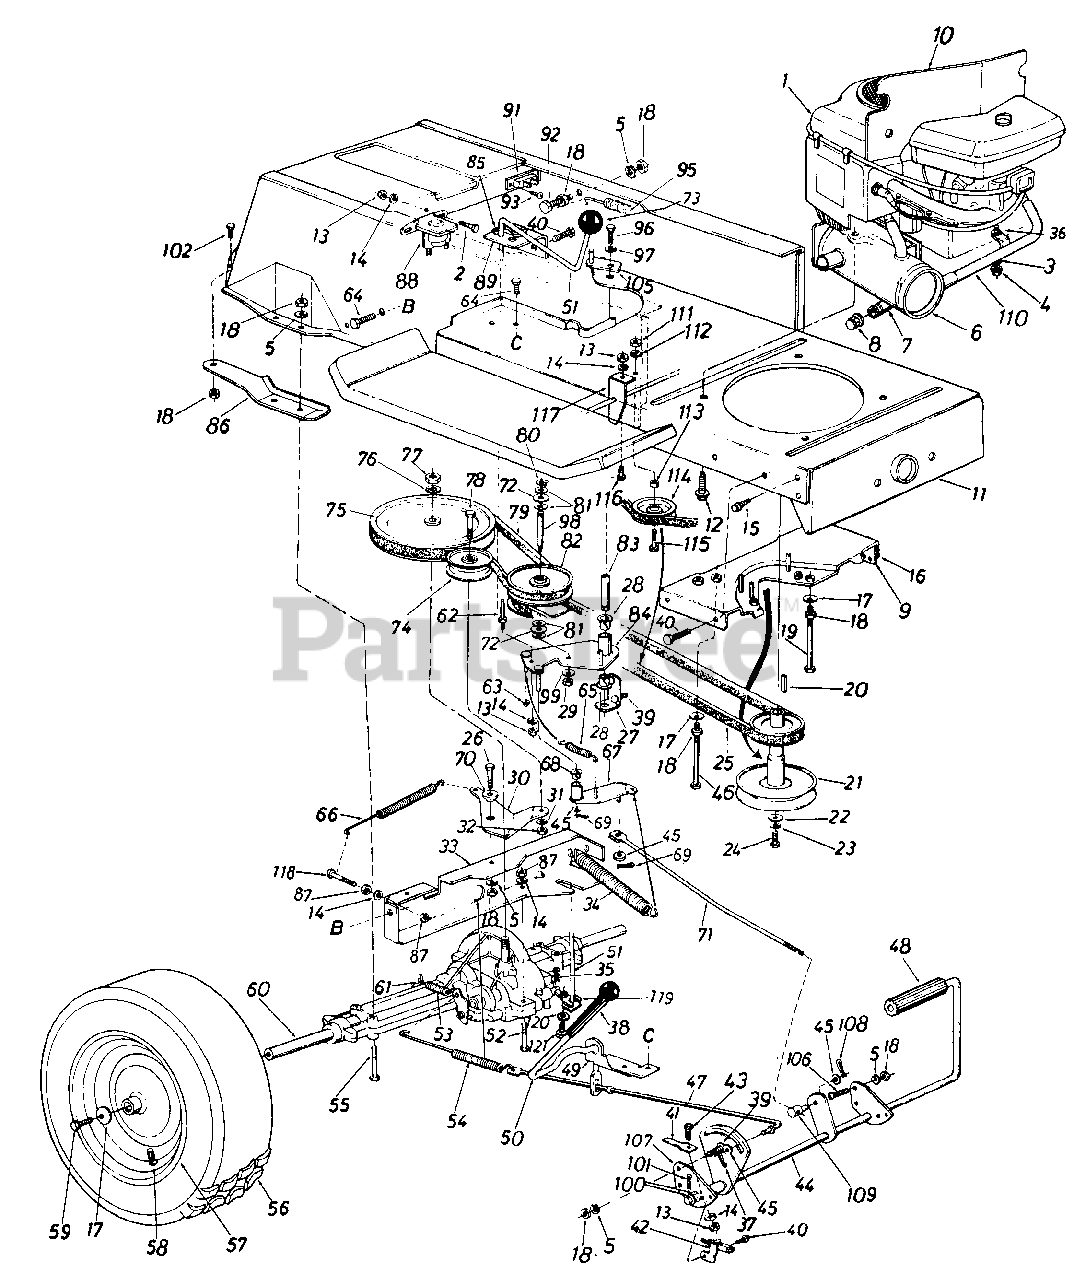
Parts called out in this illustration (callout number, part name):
1	Engine
2	Hex Bolt 1/4-20 x .62" Lg.
3	Special L-Wash. 5116" I.D.
4	Hex Nut 5/16-18 Thd.
5	L-Wash. 5/16" I.D.
6	Exhaust Muffler
7	Pipe Nipple
8	Cap Oil Drain
9	Brake Cable Brk't.
10	Heat Shield
11	Lower Frame Ass'y.
12	Hex Wash. Hd. TT-Tap Scr. 3/8-16 x 1.25" Lg.
13	Hex Nut 1/4-20 Thd.
14	L-Wash. 1/4" I.D*
15	Hex Wash. Hd. AB-Tap Scr. 5/16" x .75" Lg.
16	Belt Guard Brkt. Ass'y.
17	Bell-Wash. .345" I.D. x .88"
18	Hex Nut 5/16-18 Thd.
19	Hex Bolt 5/16-18 x 4.00"
20	Sq. Key 1/4" x 1/4" x 2.00"
21	Engine Pulley
22	Fl-Wash. 7/16" I.D. x 1.25"
23	L-Wash. 7/16" I.D.
24	Hex Bolt 7/16-20 x 1.50" Lg.
25	Variable-Speed Belt .715 x 53" Lg.
26	Hex Bolt 5/16-18 x .75" Lg.
27	Bearing Shaft Bracket Ass'y.
28	Flanged Nyliner Brg. 5/8" I.D. x .88" Lg.
29	Hex Nut 3/8-24 Thd.
30	Idler Bracket
31	L-Wash. 3/8" I.D*
32	Hex Nut 3/8-24 Thd.
33	Transaxle Support Brkt.
34	Ext. Spring .94" O.D. x 6.7
35	Inter. Cotter Pin
36	Fl-Wash. .34" I.D. x .62" O.D. x .033
37	Cotter Pin 3/32" Dia. x .75"
39	Truss Mach. Scr. 5/16-18 x .75" Lg.
40	Hex Wash. Hd. Self-Tap Scr 1/4-20 x .50" Lg.
41	Switch Actuator
42	Safety Switch
43	Hex Bolt 1/4-20 x 1.0" Lg.
44	Clutch & Brake Pedal Ass'y.
45	Fl-Wash.
46	Hex Bolt 5/16-18 x 4.51'
47	Brake Rod 20.9" Lg.
48	Foot Pad
49	Brake Lever Bracket
50	Hill Holder Brake Handle
51	Shift Lever Ass'y.
52	Hex Bolt 1/4-28 x 1.75" Lg*
53	Ext. Spring .38" O.D. x 2.5"
54	Ext. Spring .59" O.D. x 7.08"
55	Hex Bolt 5/16-18 x 2.75"
58	Air Valve
59	Hex Bolt 5/16-24 x .75" Lg.
60	Transaxle Complete R.H.
61	Brake Return Spring Anchor
62	Belt Guard Pin 1/4-20 Thd.
63	Cap Speed Nut 1/4" Dia.
64	Hex Wash. TT-Tap Scr. 5/16 x .62" Lg.
65	Ext. Spring .50" Dia.
66	Ext. Spring .62" O.D. x 6.12"
67	Variable Speed Torque Brkt. Ass'y.
68	Flanged Bearing
69	Cotter Pin 3/32" Dia.
70	Shoulder Spacer .500" Dia. x.27" Lg.
71	Speed Control Link
72	Truss Bearing .56 Dia. x 1 .25"
73	Ball Knob
74	Fl-ldler Pulley 3.25" x 1.0"
75	1/2" "V"-Pulley 8.0" O.D. x.501" I.D.
76	L-Wash. 1/2" I.D*
77	Hex Jam Nut 1/2-20 Thd.
78	Hex Bolt 3/8-24 x .75" Lg.
79	Variable Speed Belt .715 x 44" Lg.
80	Snap Ring .56" Dia.
82	Variable Speed Pulley Ass'y. 5" O.D.
83	Bearing Shaft
84	Variable Speed Brkt. Ass'y.
85	Comp. Spring Clip
86	Transaxle Support Brkt. R.H.
87	Hex Nut 1/4-28 Thd.
88	Solenoid
89	Shift Lever Bracket
91	Circuit Breaker
92	Hex Bolt 5/16-18 x 1.50"
93	Truss Hd. Phil. Scr. #10 x 1/2" Lg.
95	Ext. Spring .99" O.D. x 11.0"
96	Hex Bolt 3/8-24 x .75" Lg.
97	Bell-Wash. .38" I.D. x .88"
98	Shaft .56" Dia. x 3.875" Lg.
99	Bell-Wash. .39" I.D. x 1.12"
100	Fl-Wash.
101	Cotter Pin 3/32" Dia. x .75"
102	Hex Wash. Hd. Scr. 5/16-18 x .62" Lg.
105	Belt Guard
106	Hex Bolt 5/16-18 x .75" Lg.
107	Pedal Bracket
108	Cotter Pin 3/32 x .75"
109	Ferrule
110	Inlet Tube Ass'y.
111	Hex Nut 3/8"-16 Thd.
112	L-Wash. 3/8" I.D.
113	Fl-Wash. .390" I.D. x 1.12"
114	Fl-ldler w/ Flanges 2.750
115	Hex Bolt 3/8-16 x 2.00" Lg.
116	Hex Bolt 1/4-20 x .62" Lg.
117	Spring Hanger Bracket
118	Hex Bolt 1/4-28 x 1.25" Lg.
119	Shift Lever Link Ass'y.
120	Bell-Wash. .265 I.D. x .75 0 O.D.
121	Hex Bolt 1/4-28 x .62" Lg.
